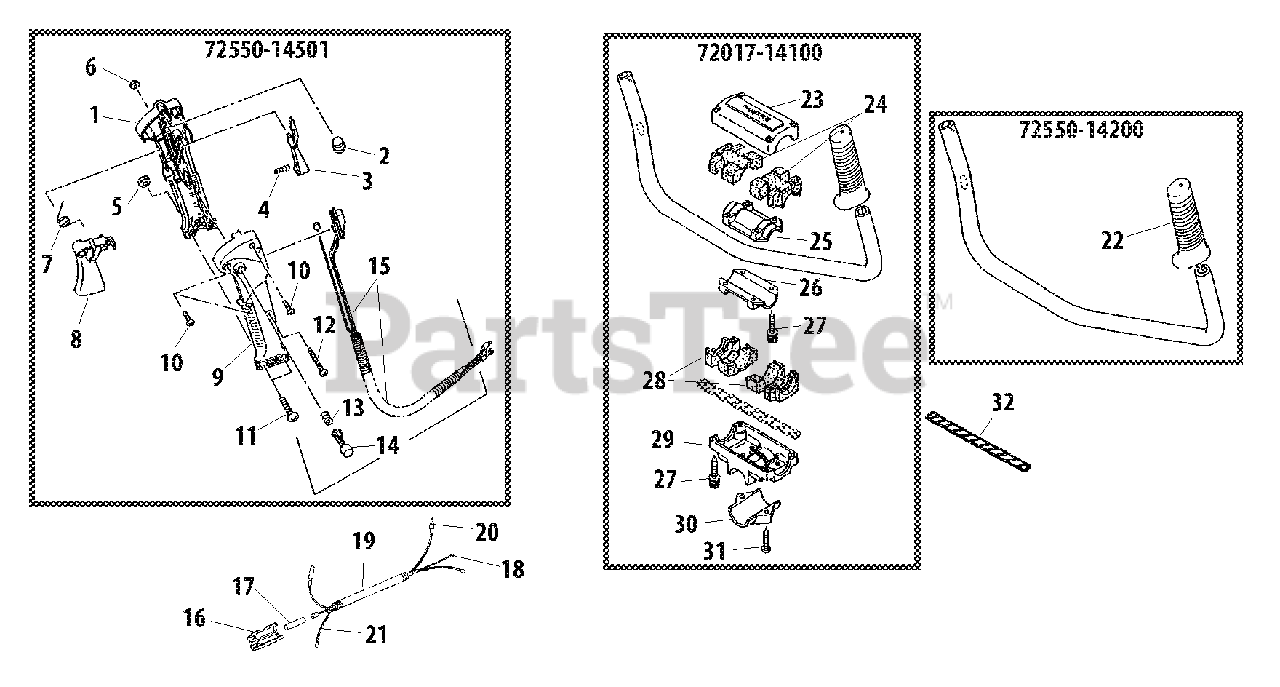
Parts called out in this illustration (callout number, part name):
1	BODY, RIGHT
2	PLUG, RUBBER
3	LOCKOUT, THROTTLE
4	SPRING, COMPRESSION
5	NUT
6	NUT M4
7	SPRING, TORSION
8	TRIGGER, THROTTLE
9	BODY, LEFT
10	SCREW - 4×16 -- TAPPING
11	SCREW M5×20
12	SCREW M4×23
13	SPRING, COMPRESSION
14	BUTTON, THROTTLE LOCK
15	CABLE, THROTTLE - A
16	CAP, DUST
17	SLEEVE
18	CABLE, THROTTLE
19	TUBE, FLEXIBLE
20	LEAD - IGNITION
21	LEAD - GROUND
22	GRIP
23	CLAMP, UPPER
24	CUSHION, UPPER
25	CLAMP, UPPER
26	CLAMP, LOWER
27	BOLT M5×25
28	CUSHION, LOWER
29	BRACKET, HANDLE Ø28
30	CLAMP, LOWER Ø28
31	SCREW M6×25
32	LEAD - GROUND
72017-14100	BRACKET KIT, HANDLEBAR
72550-14200	HANDLEBAR ASSY
72550-14501	THROTTLE LEVER ASSY
